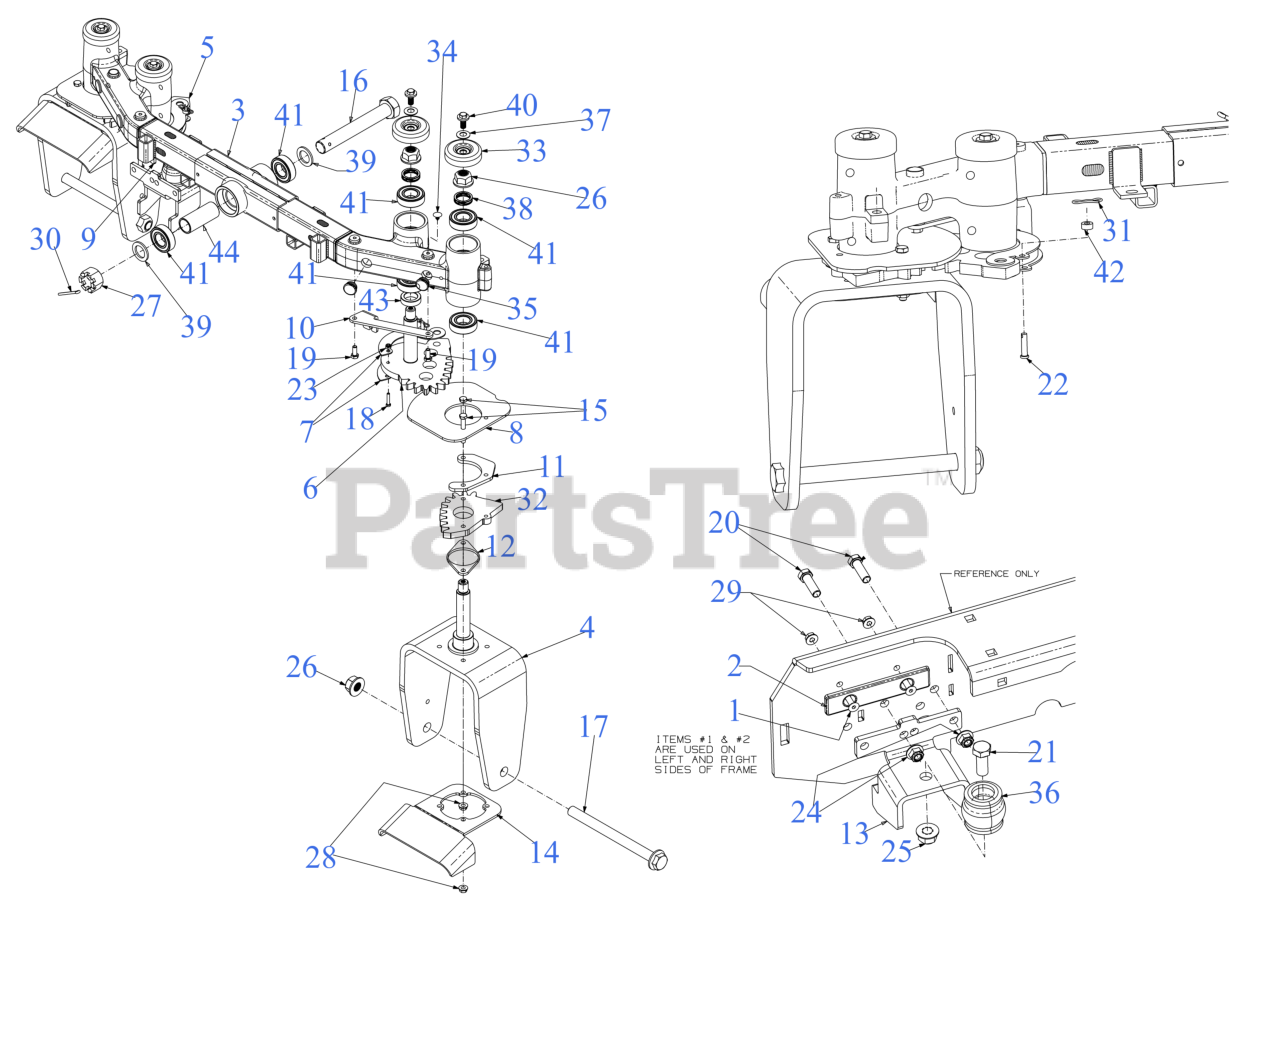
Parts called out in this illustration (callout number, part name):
1	SCREW-FLAT HEAD CA
2	PLATE-LIFT WEAR
3	AXLE ASSEMBLY
6	RIGHT HAND STEERING GEAR ASSEMBLY
12	LOWER GEAR SPACER PLATE
15	HEX SCREW 5/16-18 x 2.25 GR5
16	HEX HEAD SCREW (1-14 x 7 GR5)
17	SCREW 3/4-16 x 9.00 GR5
18	SCREW #10-24 x 1.00 GR5.1
19	SCREW 5/16-18 x .750
20	SCREW 3/8-16 x 1.25 GR5
21	SCREW 1/2-13 x 1.25 GR5
22	CLEVIS PIN .25 x 1.00
26	FLANGE LOCK NUT 3/4-16 TOP LOCK
27	CASTLE NUT 1.0-14 GR5
28	HEX FLANGE NUT
29	LOCK NUT 1/4
30	COTTER PIN
31	BOW TIE COTTER PIN 1/4-5/16
32	STEERING GEAR YOKE
33	AXLE CAP 2.5"
34	RATCHET CLIP
36	AXIAL BUMPER
37	BELL WASHER
38	WAVE WASHER
39	FLAT WASHER 1.005 x 1.570 x 0.125
41	BALL BEARING (1.0 x 52 x 15)
44	SPACER 1.00 x 1.25 x 2.99
